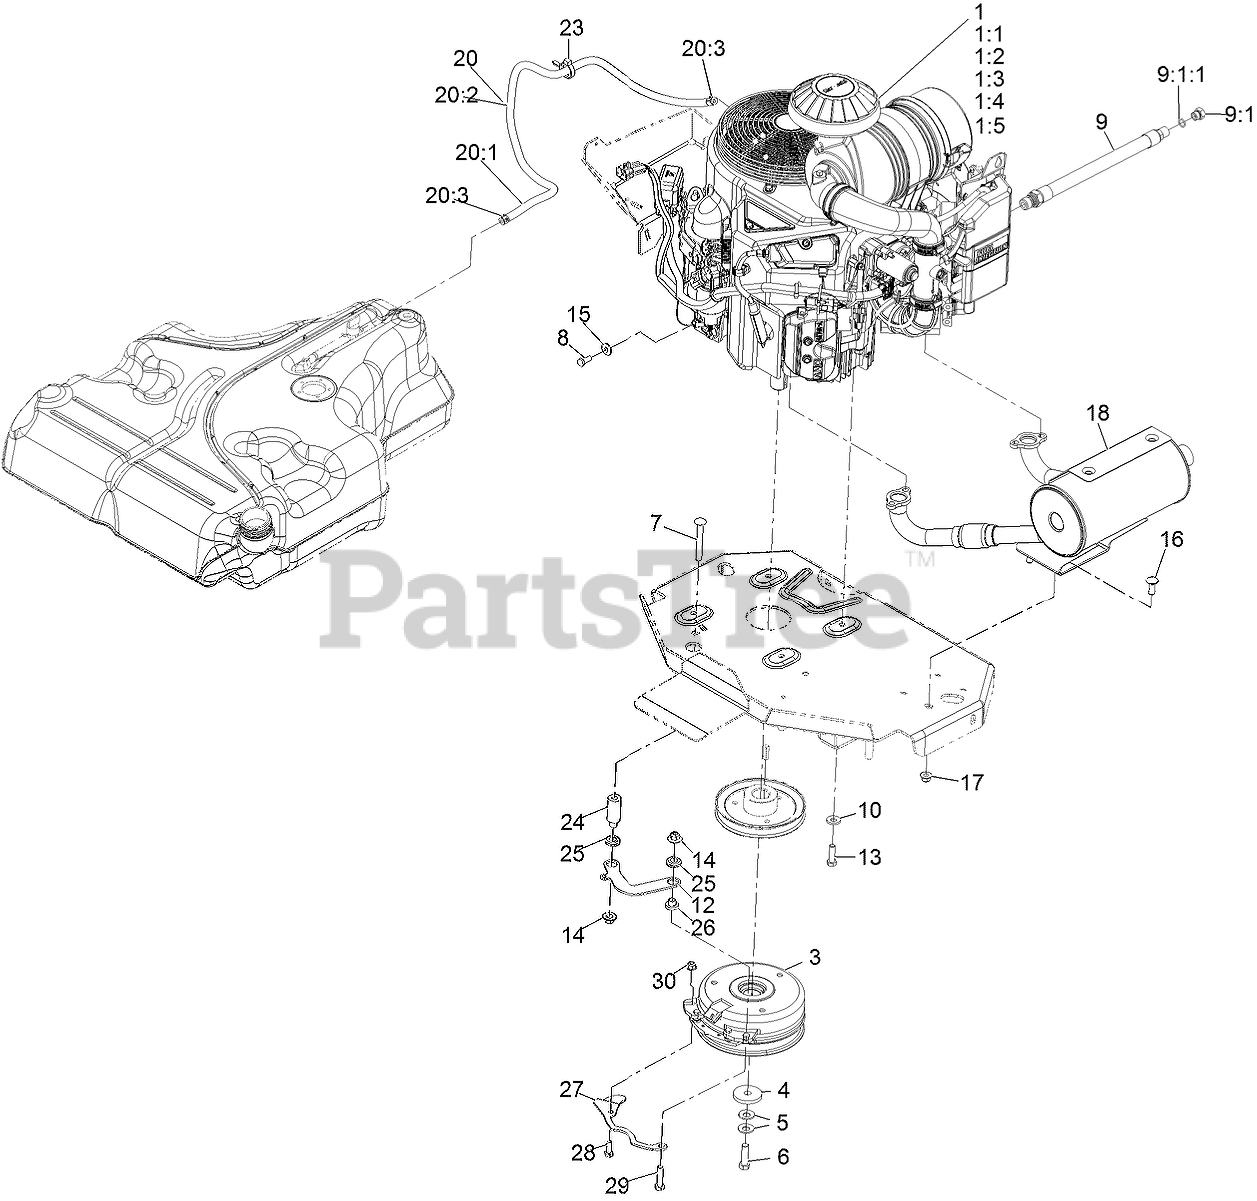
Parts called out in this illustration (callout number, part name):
1:1	Kawasaki 49065-2078 Engine Oil Filter
1:3	Kawasaki 49019-0031 Fuel Filter
1:4	Kawasaki 11013-7039 Safety Filter
1:5	Kawasaki 11013-7038 Air Filter
3	CLUTCH KIT
4	WASHER-CLUTCH
5	WASHER-SPRING
6	SCREW-HH 7/16-20 X 1 1/2 W/LOCTITE
7	SCREW-CARR
8	SCREW-HH
9	ENGINE OIL DRAIN HOSE ASM
9:1	PLUG-HH
9:1:1	O-RING
10	WASHER-BELLEVILLE
12	LINK-ANCHOR, CLUTCH
13	SCREW-HH
14	Nut-Nyloc 3/8-16 Flg
15	WASHER-SPRING
16	SCREW-CARR
17	NUT-HF, NI
18	MUFFLER, FX850/801 FLEX
20	FUEL LINE ASM
20:1	HOSE-FUEL
20:2	SLEEVE-THERMAL
20:3	CLAMP-HOSE
23	CLAMP-HOSE
25	GROMMET-RUBBER
27	BELT-GUIDE
28	SCREW-HH
29	SCREW-HH
30	NUT-HF, NI
